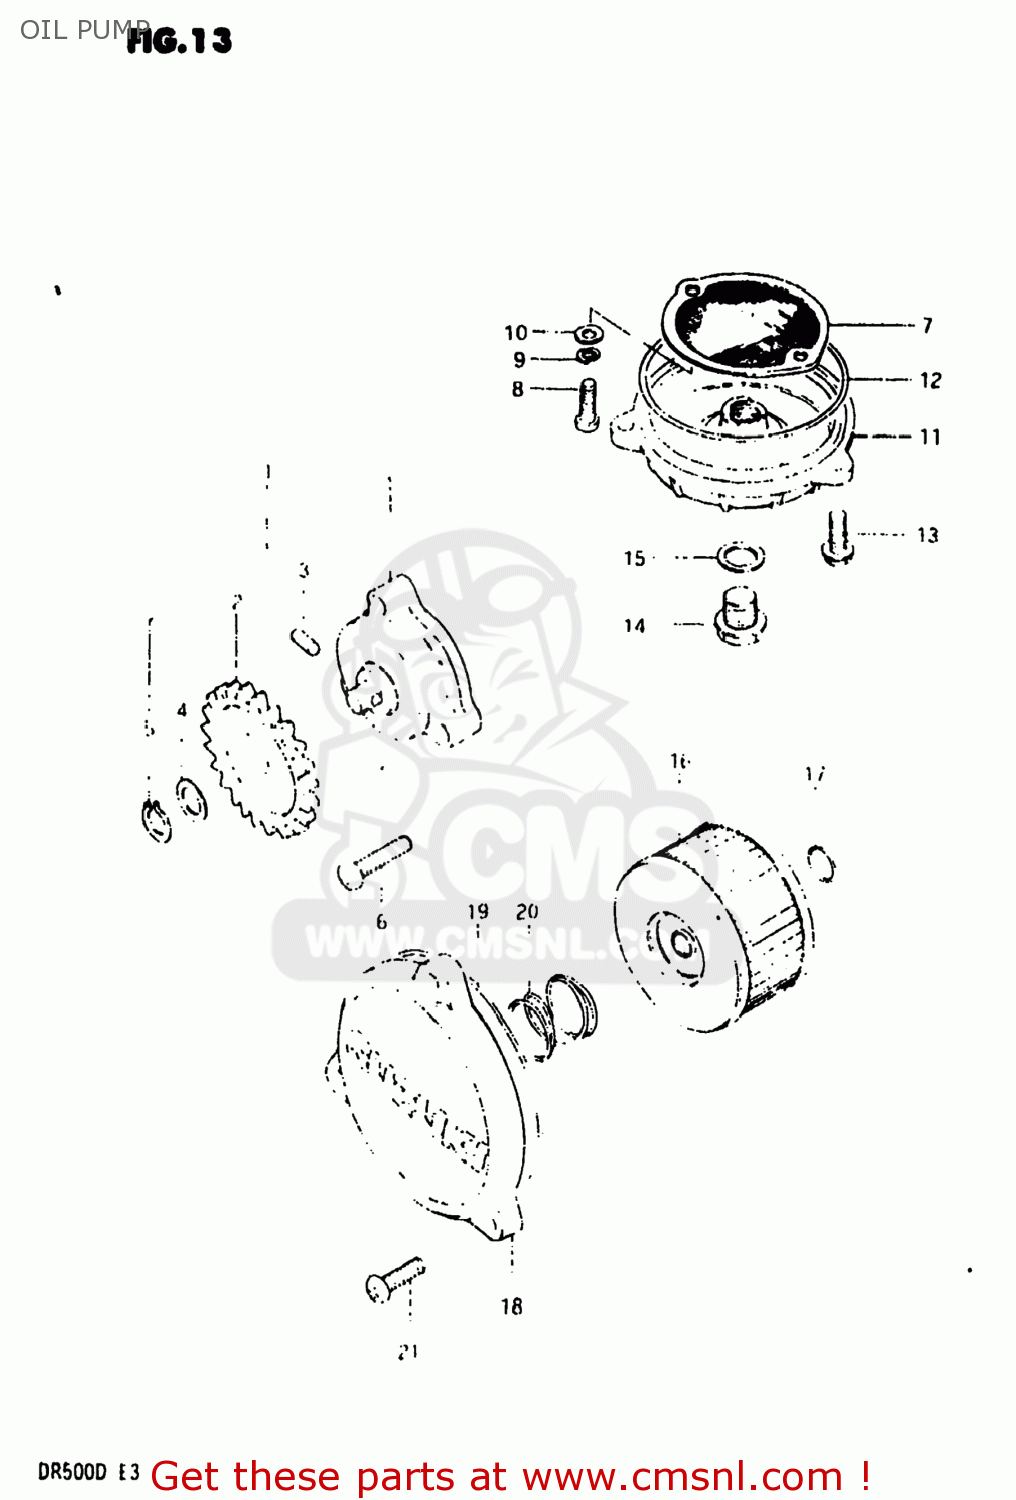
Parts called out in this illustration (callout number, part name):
1	PUMP ASSY,ENGINE OIL
2	GEAR,OIL PUMP DRIVEN
3	PIN(4X15.8)
4	SHIM
5	CIRCLIP
6	SCREW
7	STRAINER,ENGINE OIL
8	SCREW
9	LOCK WASHER
10	WASHER
11	CAP,OIL STRAINER
12	O RING(D:2.4,ID:85)
13	BOLT,REAR
14	PLUG
15	GASKET(14X19.2X2) (NAS)
16	FILTER,ENGINE OIL
17	O RING(D:2.4,ID:15.8)
18	CAP,ENGINE OIL FILTER
19	O RING(D:2.4,ID:73)
20	SPRING
21	SCREW
